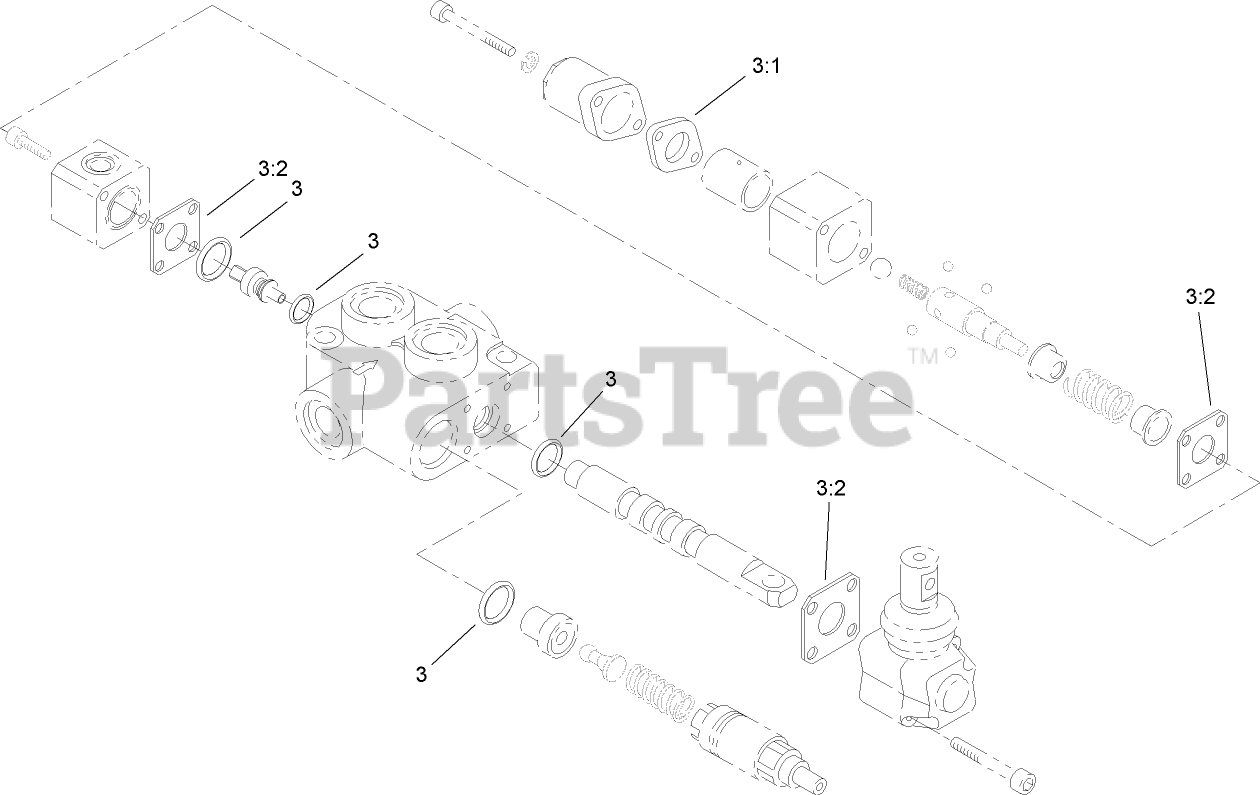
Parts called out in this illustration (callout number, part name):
3	SEAL KIT
3:1	GASKET
3:2	GASKET
